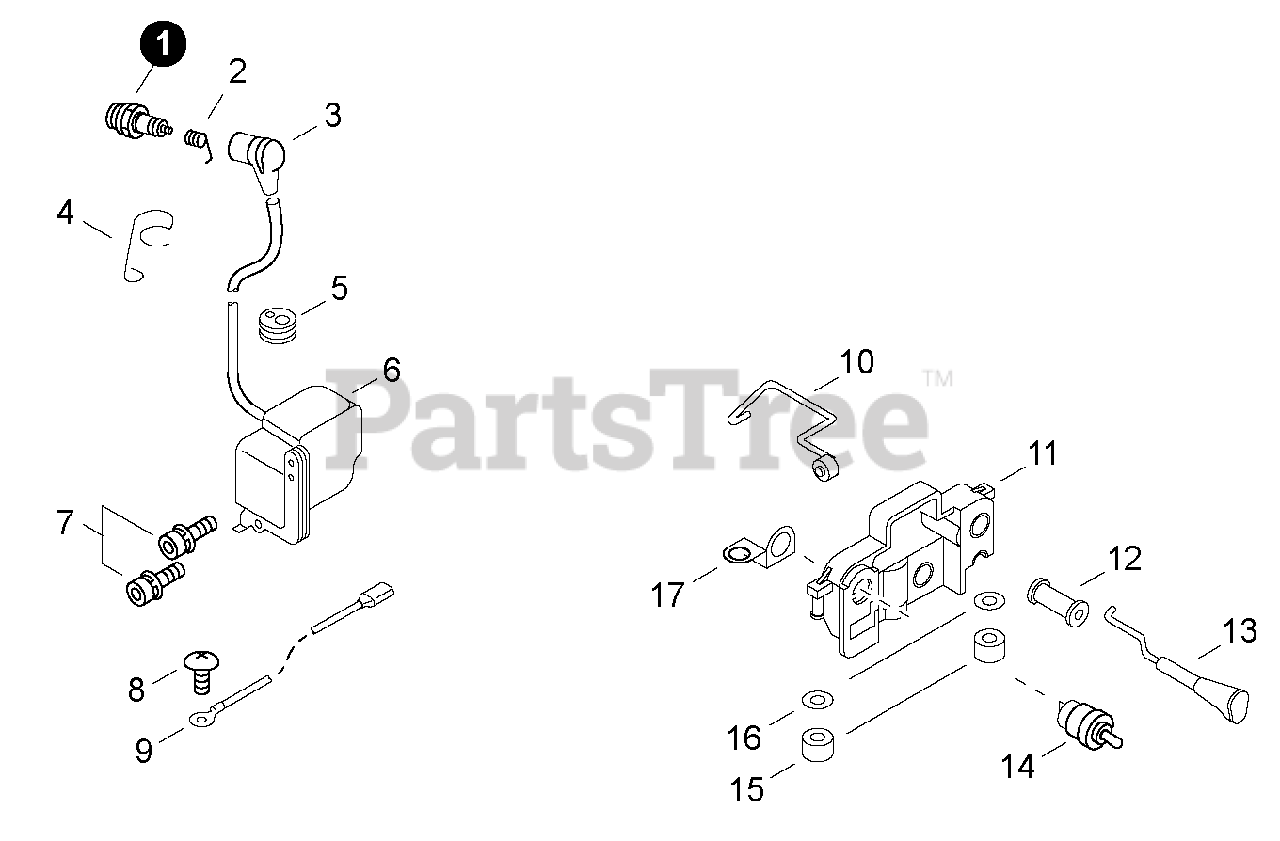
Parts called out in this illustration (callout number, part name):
1	SPARK PLUG - BPMR7A
2	TERMINAL, SPARK PLUG
3	CAP, SPARK PLUG
4	GUIDE, CORD
6	COIL, IGNITION
7	BOLT 5×22
8	SCREW 4×6
9	LEAD - GROUND
10	ROD, THROTTLE
11	BRACKET, SWITCH
12	GROMMET, CHOKE
13	ROD, CHOKE
14	SWITCH, ON-OFF
16	WASHER, FLAT 5.5×10×0.8
17	TERMINAL, SWITCH
